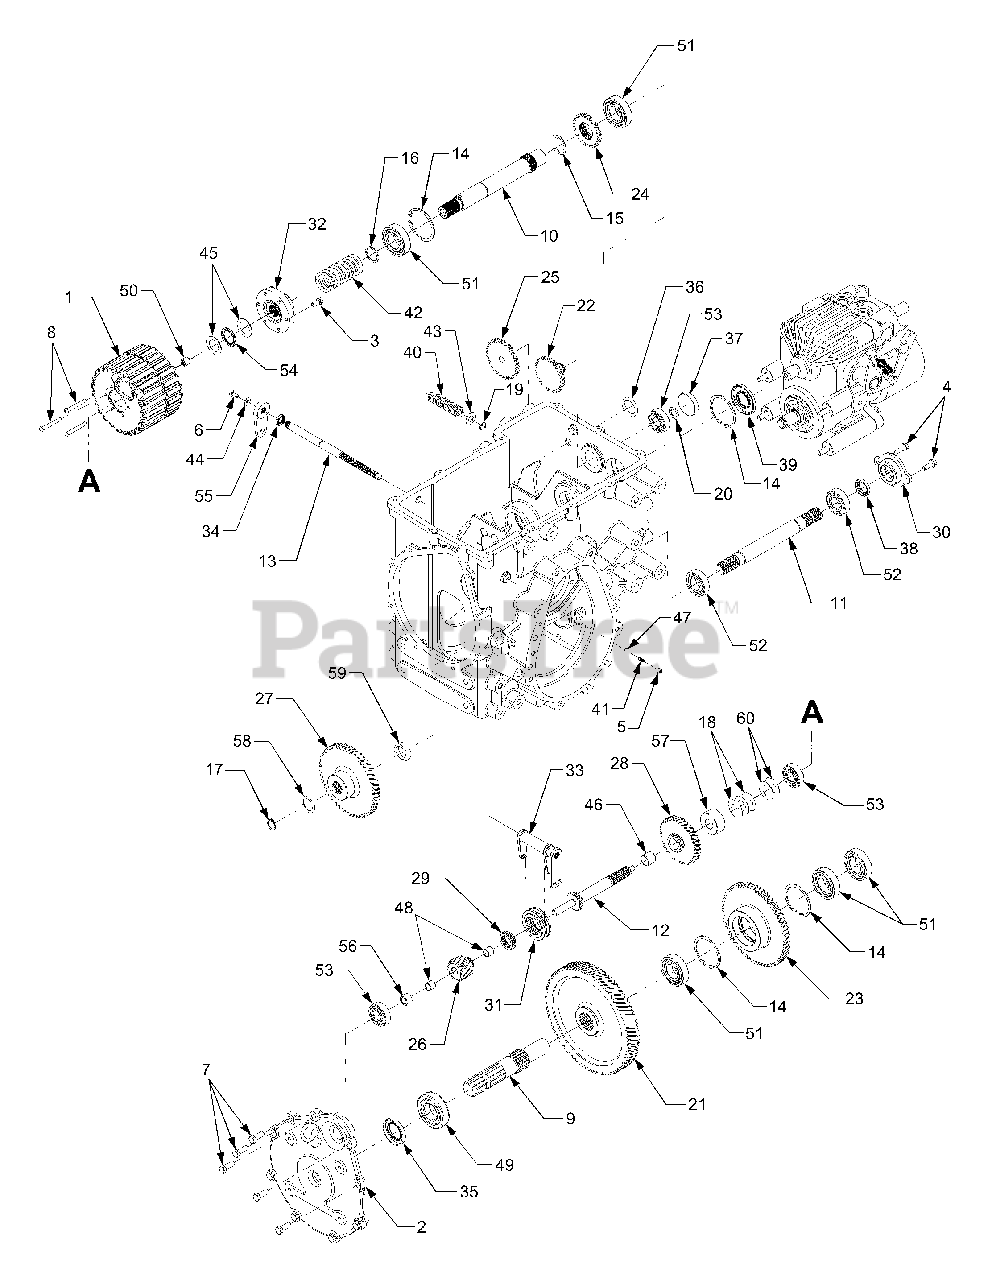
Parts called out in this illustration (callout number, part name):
1	Clutch Assembly, PTO
2	Housing, Rear
3	Screw, Hex Cap Lock, 1/4-20 x .62
4	Screw, Hex Wash Hd, 5/16-18 x .875 GR5
5	Screw, Cup Set, 5/16-18 x 3/8
6	Screw, Hex Cap, 1/4-20 x .5 GR5
7	Screw, Hex Cap Lock, 3/8-16 x 1.0 GR5
8	Screw, Round Hd, 6mm x 40mm
9	Shaft, 540 PTO
10	Shaft, Input
11	Shaft, 2000 PTO
12	Shaft, PTO Back
13	Shaft, PTO Actuator
14	Ring, Retaining
15	Ring, Retaining
16	Ring, Retaining
17	Ring, Retaining
18	Washer, Flat, .793 x 1.368 x .01
19	Ring, Retaining
20	Ring, Retaining
21	Gear, 540 PTO: 81T
22	Gear, Auxiliary Drive Idler: 28T
23	Gear, 2000 PTO: 61T
24	Gear, Auxiliary Drive Pinion: 28T
25	Gear, Auxiliary Drive: 32T
26	Gear, 540 PTO Pinion: 14T
27	Gear, 2000 PTO Pinion: 54T
28	Gear, 2000 PTO Pinion: 34T
29	Gear, Spline Coupling
30	Cover, 2000 PTO
31	Collar, 2 Speed
32	Coupling, PTO
33	Actuator, PTO
34	Seal, Oil
35	Seal, Oil
37	Plug, Oil
38	Seal, Oil
39	Seal, Oil
40	Spring, Compression
41	Spring, Detent
42	Spring, Compression
43	Washer, Flat, .56 x 1.0 x .040
44	Washer, Flat, .25 x .630 x .0515
45	Washer, Thrust, 1.007 x 1.542 x .03
46	Bearing, Sleeve, 20mm x 23mm x 20mm
47	Ball, Detent
48	Bearing, Sleeve, 13mm x 15mm x 10mm
49	Bearing, Ball
50	Bearing, Needle
51	Bearing, Ball
52	Bearing, Ball
53	Bearing, Ball
54	Bearing, Needle Thrust
55	Arm, PTO Select
56	Spacer, 13mm x 20mm x 14mm
57	Spacer, .80 x 1.85 x .855
58	Washer, Flat, .865 x 1.145 x .03
59	Spacer, .980 x 1.25 x .420
60	Washer, Flat, .793 x 1.368 x .025
